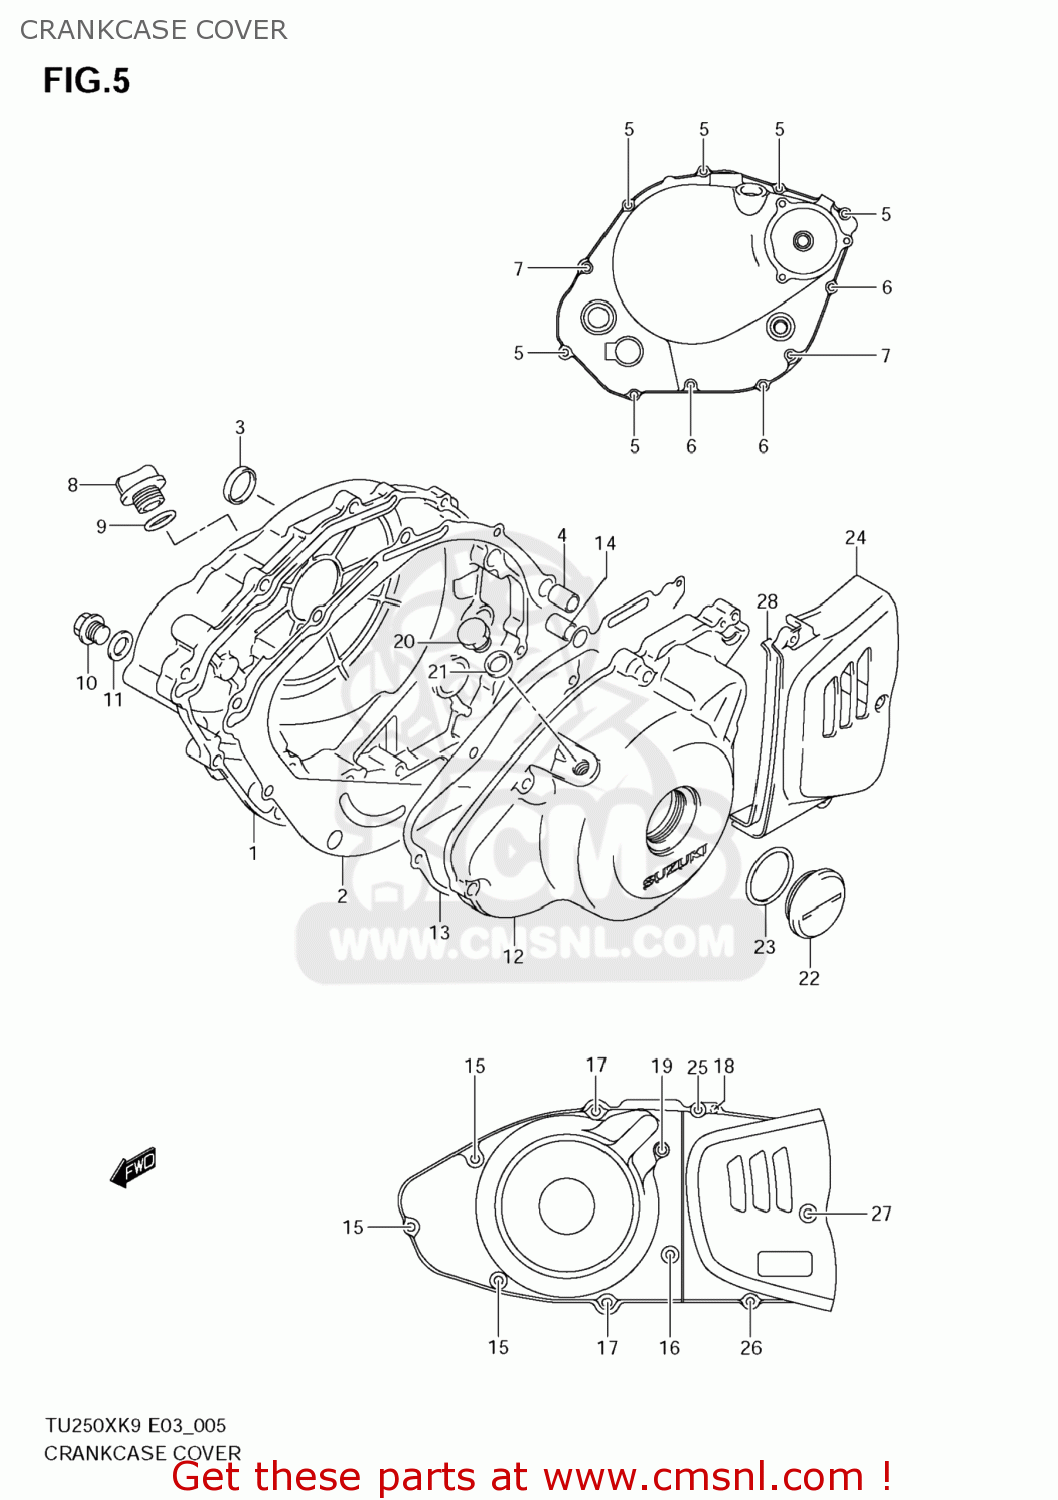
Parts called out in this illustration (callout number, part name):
1	COVER,CLUTCH
2	GASKET,CLUTCH COVER (NAS)
3	PLUG,CLUTCH COVER KICK
4	PIN
5	BOLT(6X25)
6	BOLT(6X35)
7	BOLT(6X45)
8	PLUG(20X10)
9	O RING(D:3.1,ID:16.8)
10	PLUG (14X12)
11	GASKET(13.8X18.8X4.8) (NAS)
12	COVER,MAGNETO
13	GASKET,MAGNETO COVER (NAS)
14	PIN
15	BOLT(6X25)
16	BOLT(6X35)
17	BOLT(6X50)
18	BOLT
19	BOLT(6X60)
20	PLUG,12X9
21	GASKET(12.1X16.2X3.7) (NAS)
22	PLUG,36X10
23	O RING(D:3.1,ID:32.7)
24	COVER,ENGINE SPROCKET
25	BOLT(5X20)
26	BOLT(5X30)
27	BOLT(5X45)
28	DAMPER,ENGINE SPROCKET COVER
